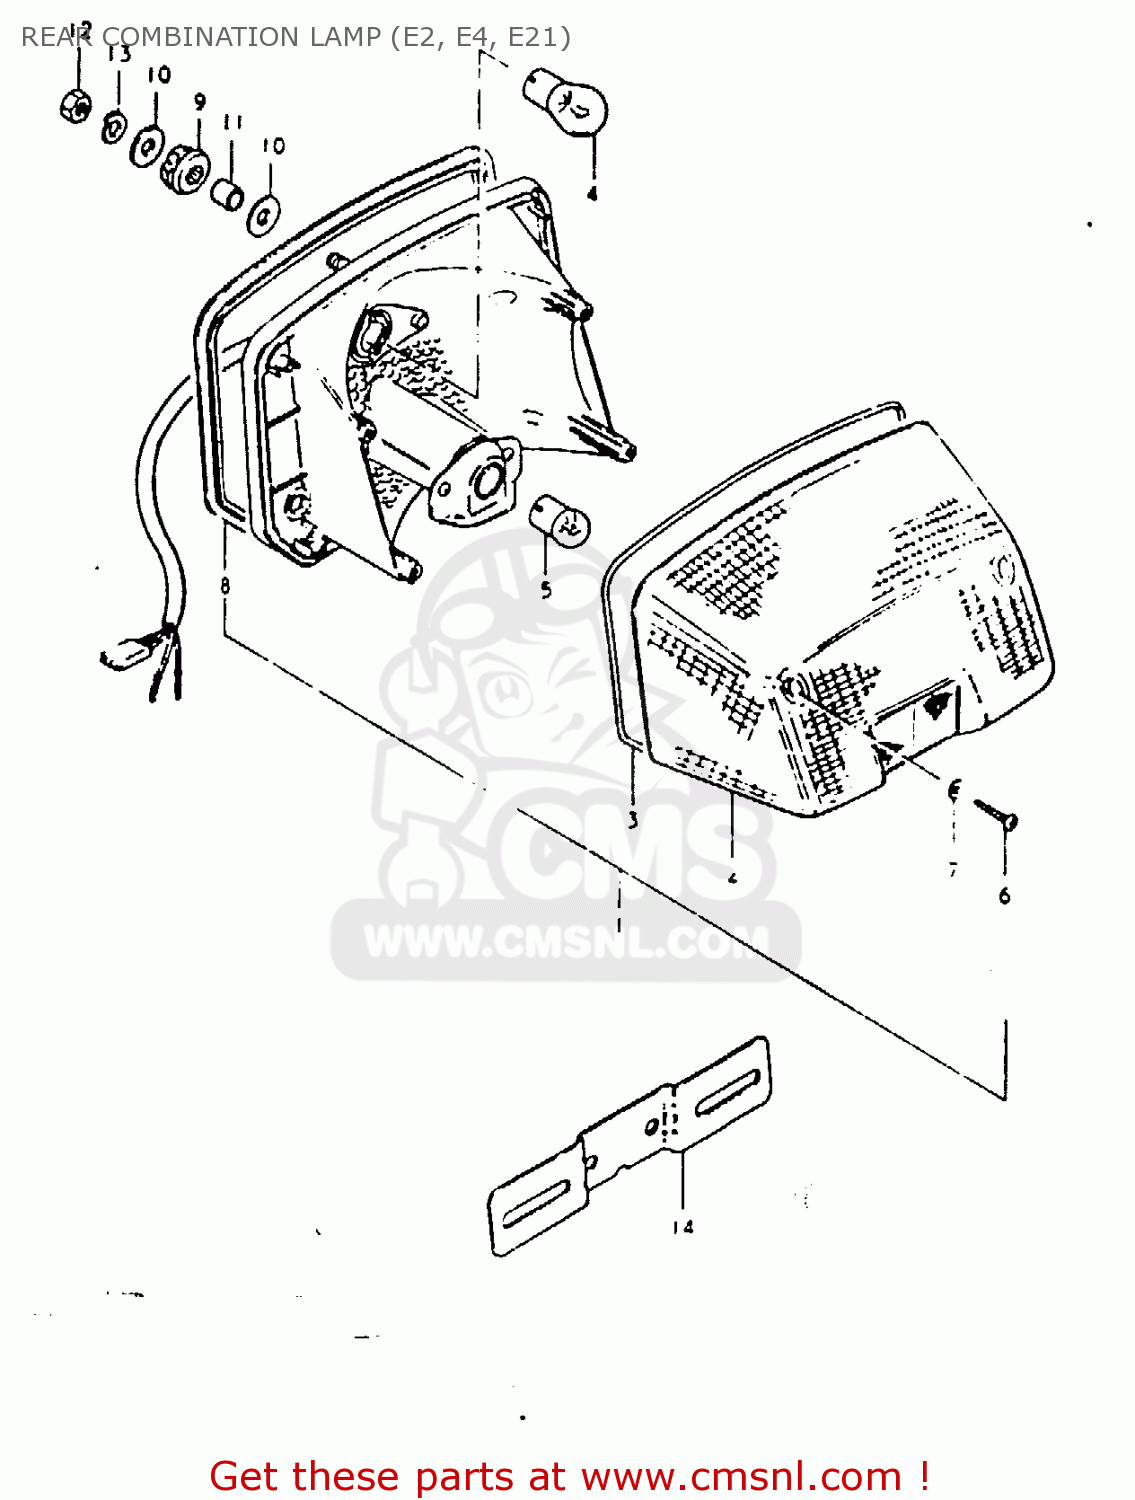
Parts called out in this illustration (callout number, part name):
1	LAMP ASSY, TAIL
2	LENS
3	GASKET (NAS)
4	BULB 12V21/5W
5	BULB
6	SCREW
7	GASKET (NAS)
8	GASKET,REAR COMBINATION LAMP
9	CUSHION
10	WASHER
11	SPACER (6.8X10X11.5)
12	NUT
13	LOCK WASHER
14	PLATE, LICENSE
